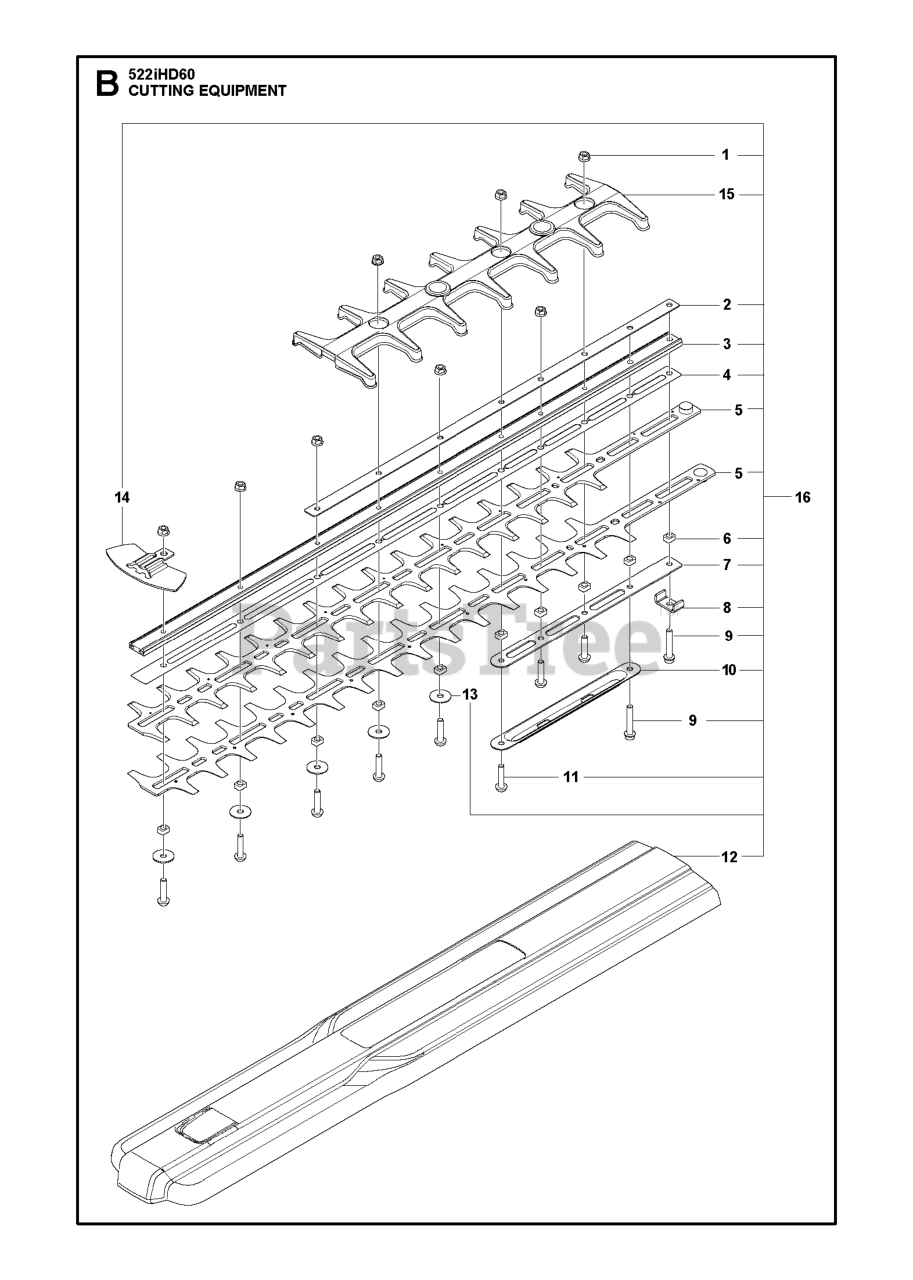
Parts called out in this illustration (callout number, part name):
1	NUT HEXAGON LOCK WITH FLANGE M
2	BAR PLATE UPPER
3	GUIDE BAR HD/HS60
4	WEAR PLATE
7	BAR PLATE LOWER
10	BAR PLATE LOWER
11	SCREW HEXALOBULAR SOCKET BUTTO
13	WASHER PLAIN 5.5X19X1.2 ST TBO
14	PROTECTION BLADE TIP
15	PROTECTOR BAR ASSY HUSQVARNA
